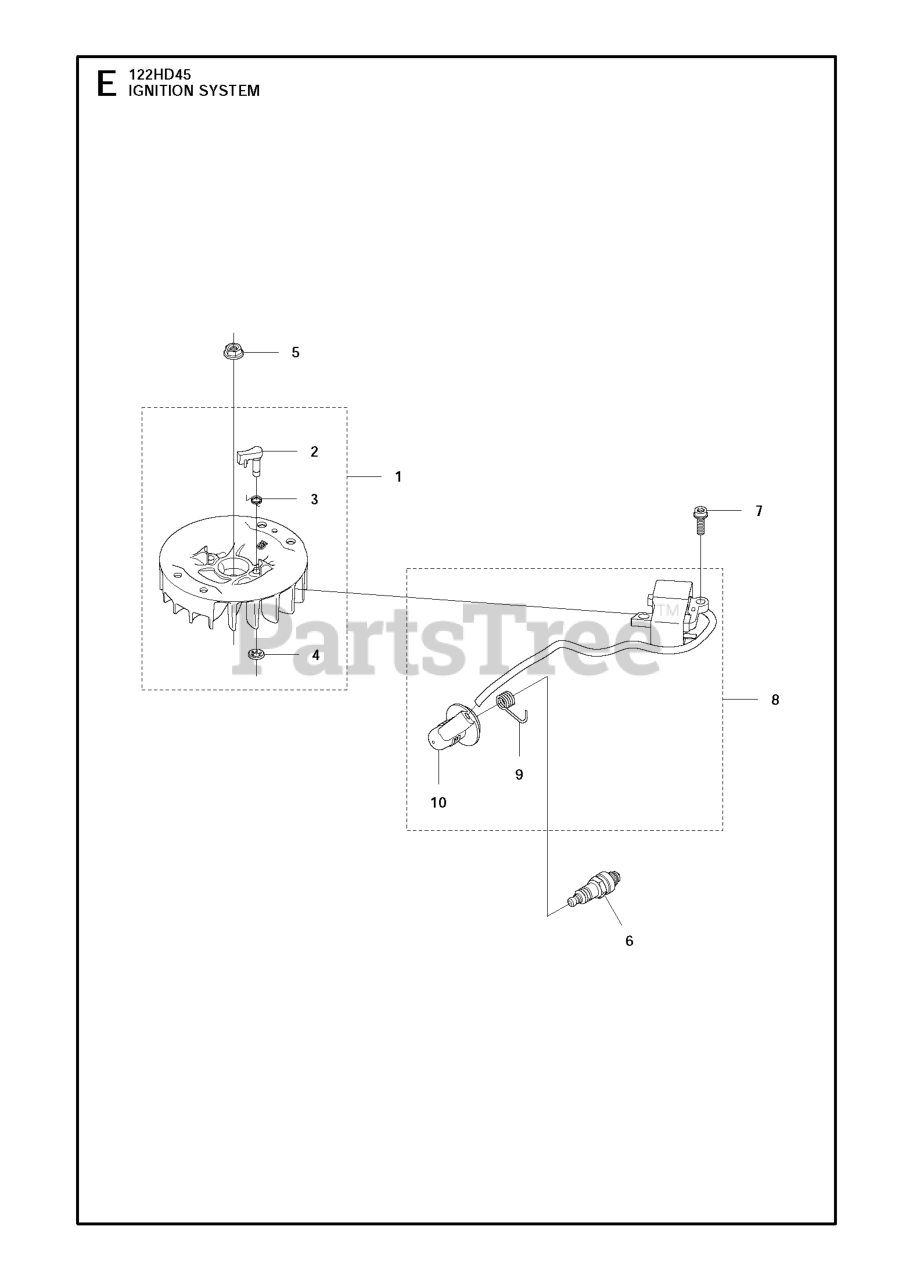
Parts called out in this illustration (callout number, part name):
2	STARTER PAWL
3	LOCKNUT M8
4	LOCK WASHER
5	FLANGE NUT
6	SPARK PLUG HQT-4 RESISTOR
8	IGNITION MODULE A051
9	SPRING
10	CAP SPARK PLUG
11	BALL BEARING 6004-2RS1
19	IDLER PULLEY
21	BELT TENSIONER
29	WASHER
31	SCREW
39	RETAINING RING SGA 20
45	WASHER
47	SCREW
54	WASHER
57	Retaining Ring Sga 16
63	WASHER BRB 8.4X17
64	LOCKNUT M8
